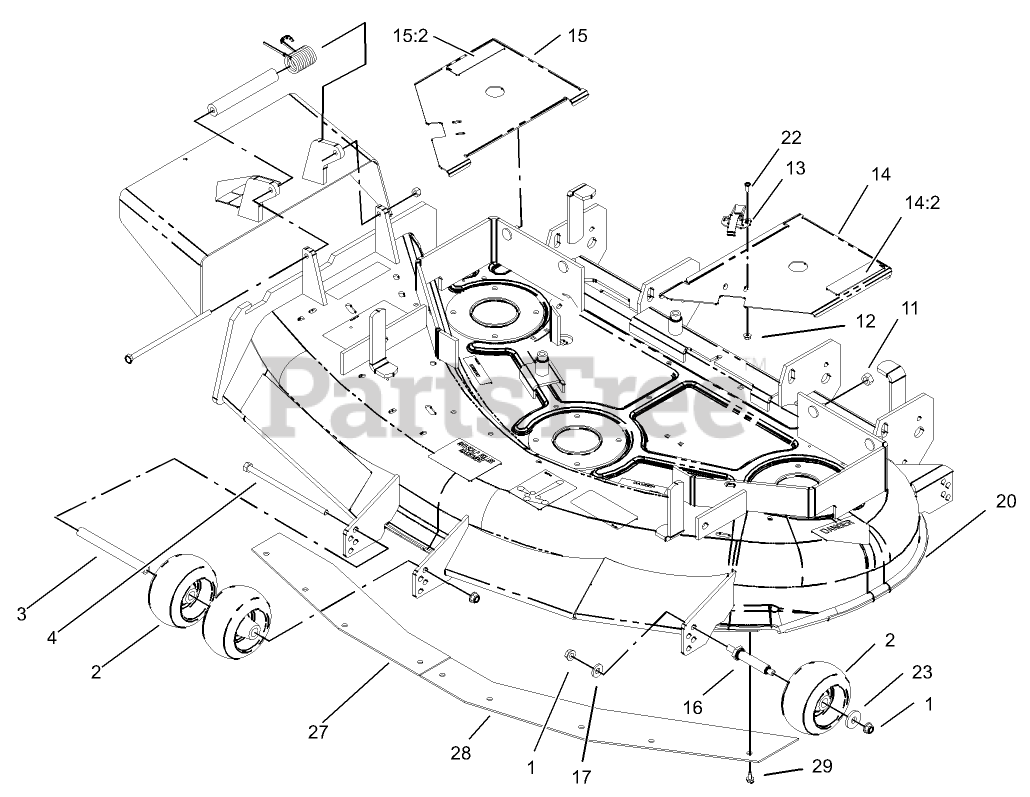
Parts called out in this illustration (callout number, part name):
1	NUT-HHF, WHIZ
2	WHEEL-GAGE
3	SPACER-WHEEL
4	SCREW-HH
7	SPRING-TORSION
8	SCREW-HH
9	Deflector ASM
9:2	DECAL-DANGER
10	NUT-LOCK, NI
11	NUT-LOCK, CONE
12	NUT-LOCK, FLANGE
13	CLAMP-SLOTTED
14	LH COVER ASM
14:2	DECAL-WARNING
15	RH COVER ASM
15:2	DECAL-WARNING
16	SPACER
17	WASHER-BELLEVILLE
20	DECK AND DEFLECTOR ASM
22	SCREW-HWH
23	WASHER
27	PLATE-BLOWOUT, RH
28	PLATE-BLOWOUT, LH
29	SCREW
30	SPACER
